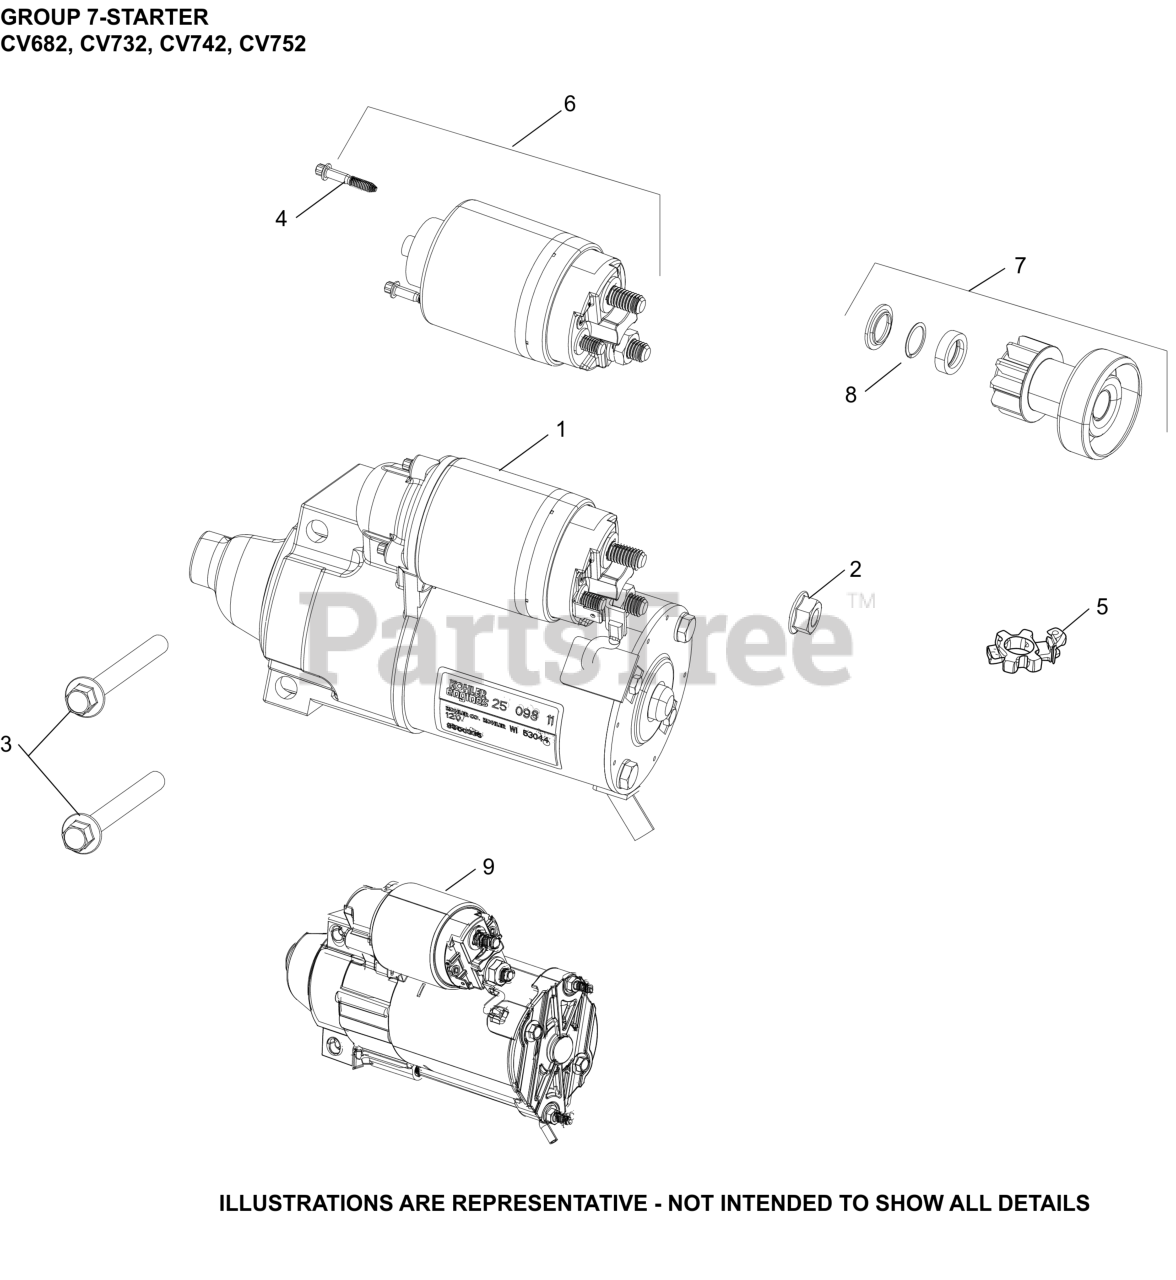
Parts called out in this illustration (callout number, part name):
2	NUT, FLG M8X1.25
3	SCREW, FLG M8X1.25X80
NI	STARTER, SOLENOID SHIFT
